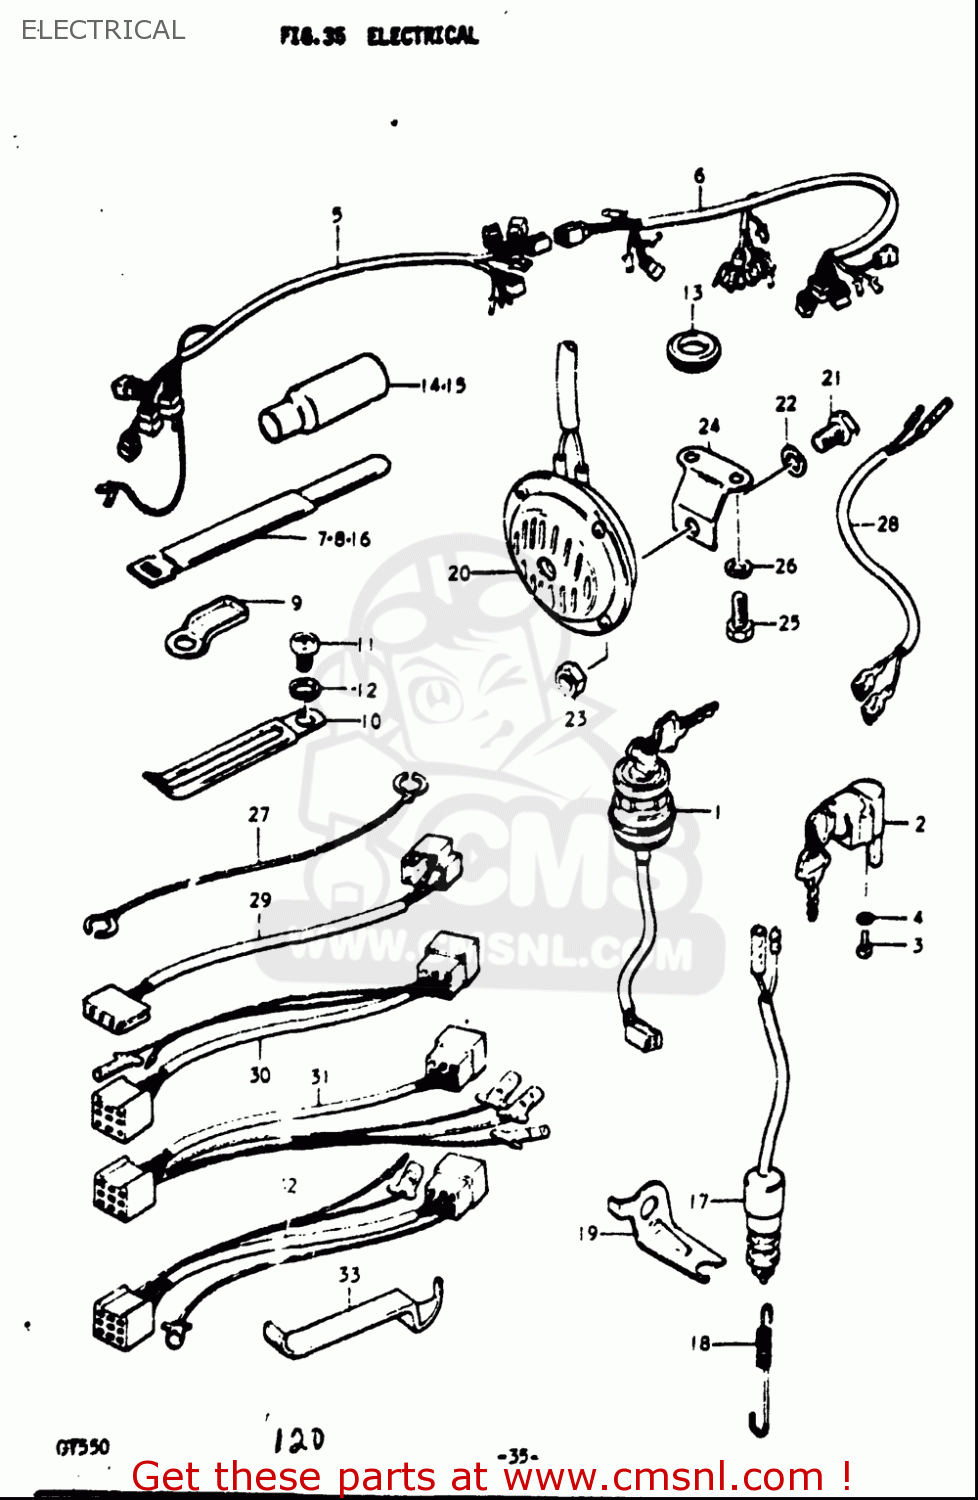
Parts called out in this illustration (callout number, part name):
1	SWITCH ASSY,IGNITION
2	LOCK ASSY,STEERING
3	SCREW
4	WASHER,LOCK
7	CLAMP
9	CLAMP
10	CLAMP(L:80 T:1.0)
11	SCREW
12	WASHER,LOCK
14	BOOT,WIRING HARNESS
16	CLAMP
17	SWITCH,BRAKE LAMP
18	SPRING
19	BRACKET, BRAKE LAMP SWITCH
20	HORN ASSY
21	BOLT
22	WASHER,LOCK
23	NUT
25	BOLT
26	WASHER,LOCK
27	LEAD WIRE,EARTH
28	WIRE,HORN LEAD
29	LEAD WIRE,HEADLAMP
